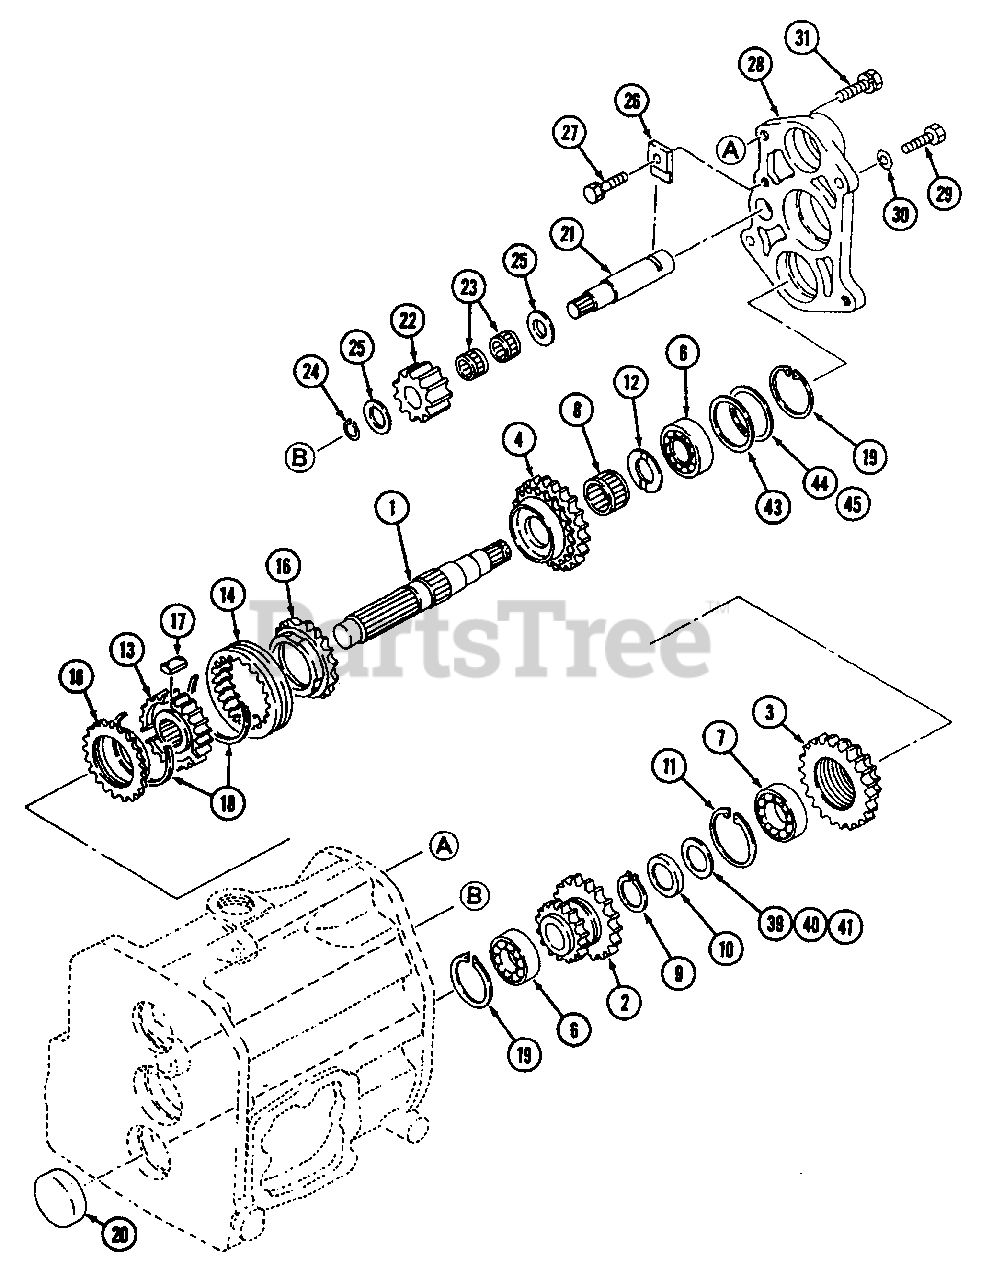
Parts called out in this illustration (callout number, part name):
1	Shaft,Main Change
3	Gear, 36T Back
20	Seal Cap (2WD)
